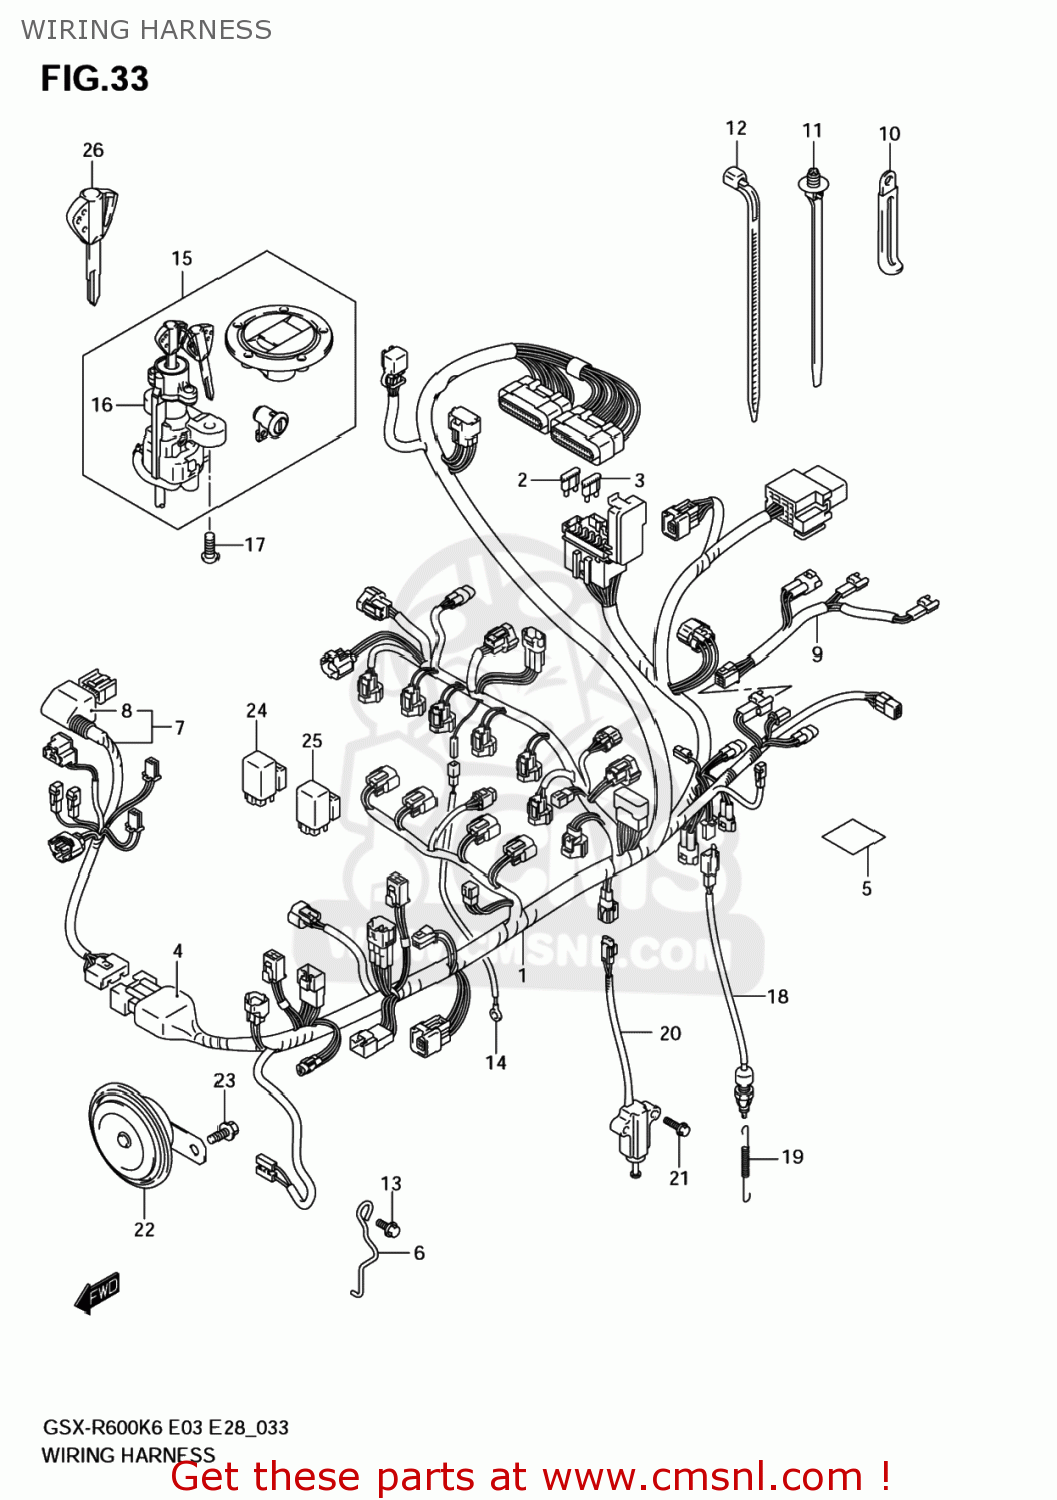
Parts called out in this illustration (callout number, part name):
1	HARNESS,WIRING NO.1
2	FUSE(10A)
3	FUSE(15A)
4	COVER
5	PROTECTOR(30X80X1)
6	GUIDE,WIRING HARNESS
7	HARNESS,WIRING NO.2
8	COVER,CONNECTOR
9	WIRE,RR COMB
10	CLAMP(L:45)
11	CLAMP(L:154)
12	CLAMP(L:125)
13	BOLT
14	WIRE,OIL PRESSURE SWITCH LEAD
15	LOCK SET
16	LOCK ASSY,STEE
17	BOLT(8X20)
18	SWITCH ASSY,STOP LAMP
19	SPRING
20	SWITCH ASSY,SIDE STAND
21	BOLT
22	HORN ASSY
23	BOLT
24	RELAY ASSY
25	RELAY ASSY
26	KEY,BLANK
